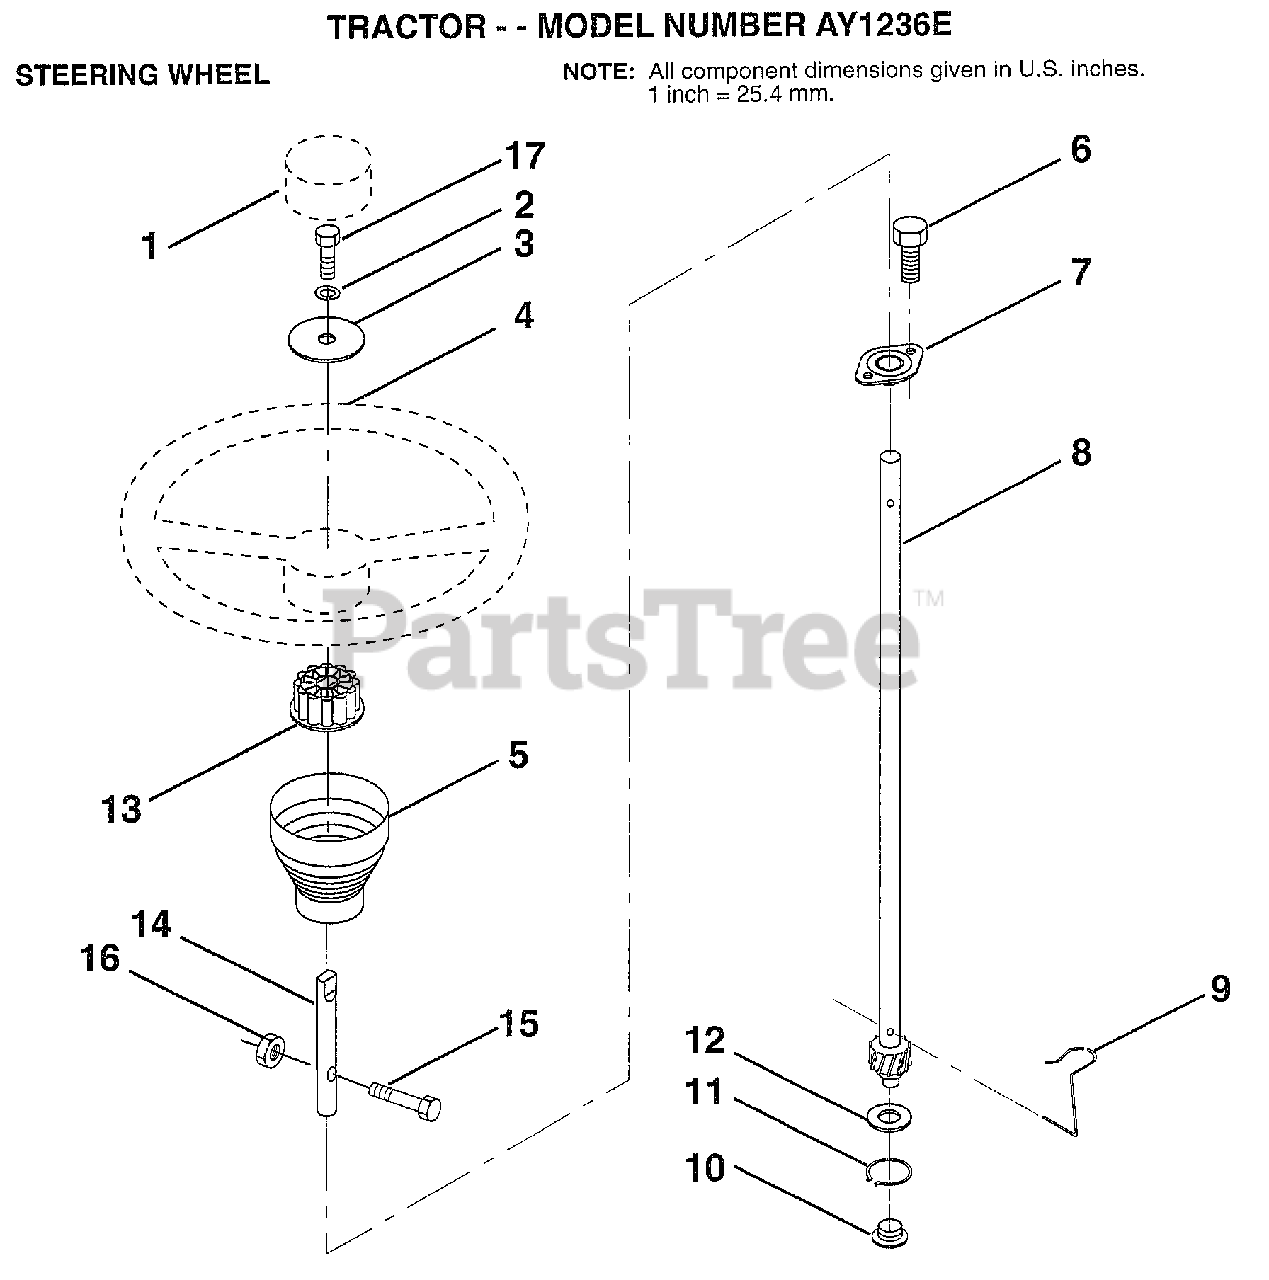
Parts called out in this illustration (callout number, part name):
1	ST WHL INSERT CAP
2	LOCKWASHER
3	WASHER T
5	SLEEVE STEERING
6	"SCREW-TT,10-32 FL"
7	BUSHING.STR.623
8	SHAFT.STEERING.LR
9	STEERING CLIP
10	BUSHING STEER LWR
11	RING
12	WASHER LT
13	ADAPTER LT
14	EXT SHAFT STEERIN
15	BOLT
16	NUT
17	BOLT
